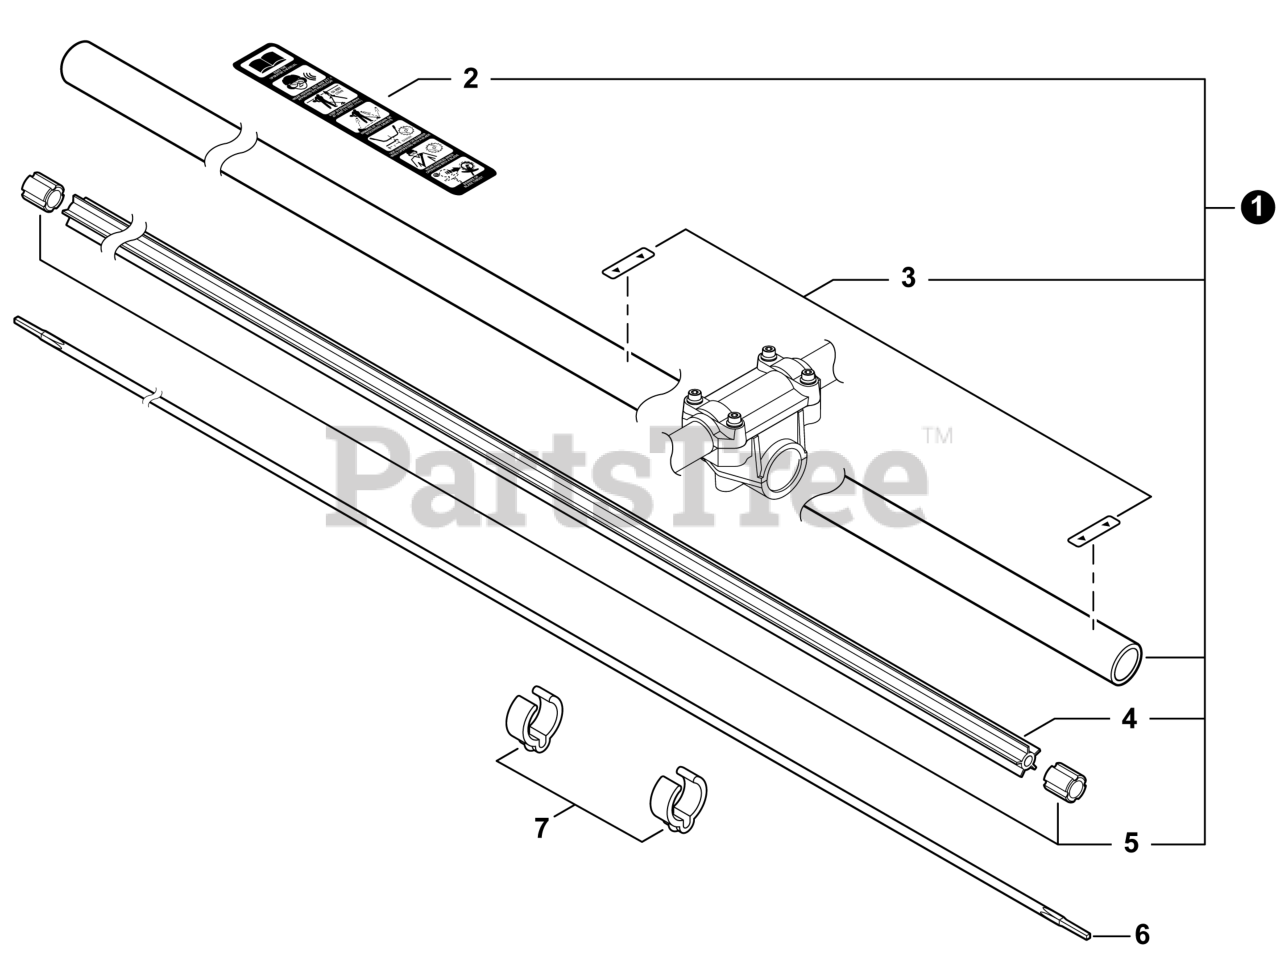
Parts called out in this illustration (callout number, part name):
1	MAIN PIPE ASSY
2	LABEL - CAUTION (BLADE CAPABLE)
3	LABEL - ALIGNMENT
4	LINER, FLEXIBLE 21.6×1420
6	DRIVESHAFT - FLEXIBLE
7	CLIP, CABLE 25 MM
